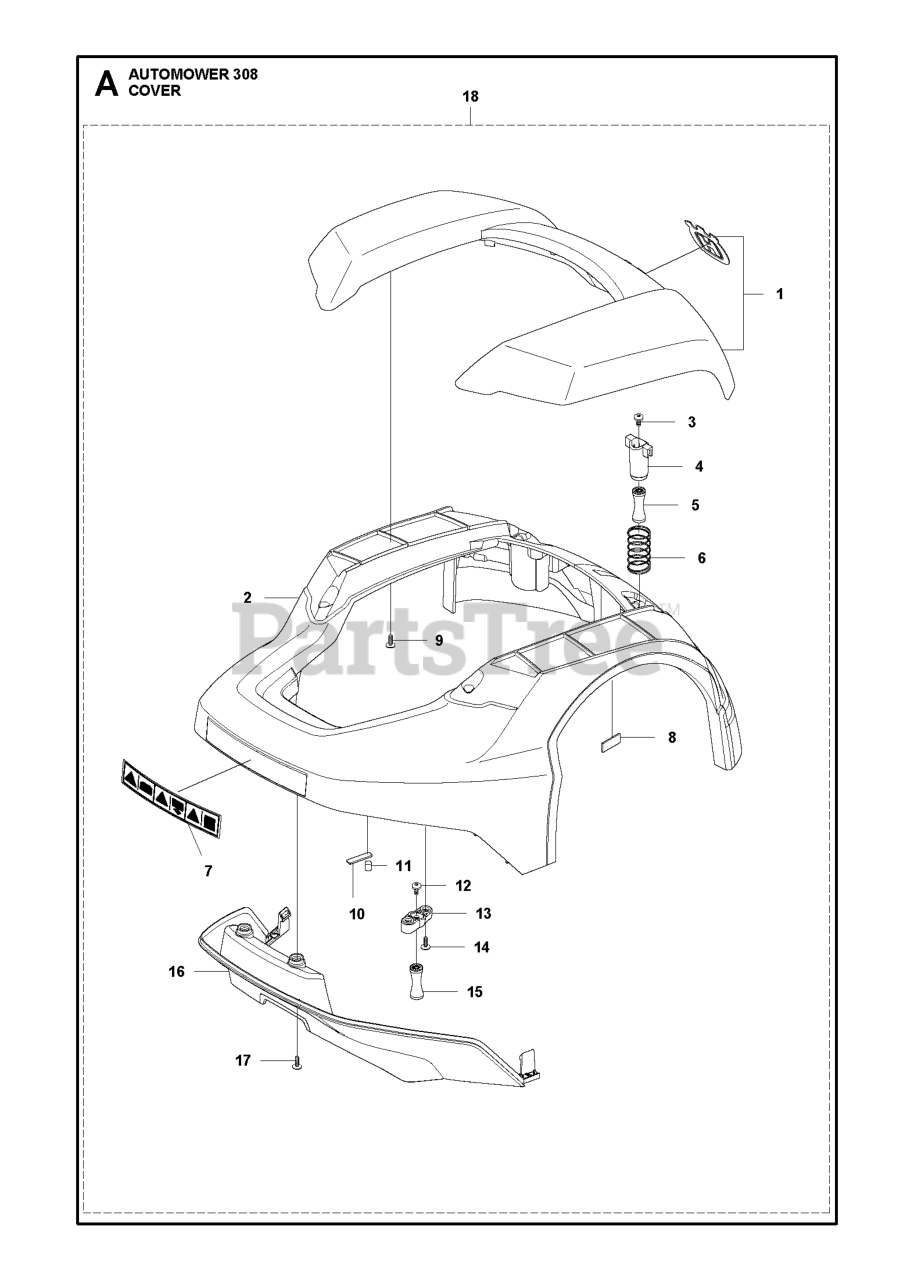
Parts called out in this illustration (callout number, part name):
3	SCREW ITXPANM M5X12 8.8 ZP-BC
4	BRACKET COLUMN FRONT USE WITH
5	DAMPER RUBBER 40 SHORE
6	SPRING LIFT SENSOR L = 35 MM
8	MAGNET LIFT SENSOR
9	SCREW 14MM
10	PLATE CARRIER MAGNET
11	MAGNET COLLISION SENSOR
12	SCREW ITXPANM M5X12 8.8 ZP-BC
13	SUPPORT CLAMP USE WITH M5 X 1
14	SCREW 14MM
15	DAMPER RUBBER 40 SHORE
17	SCREW 14MM
